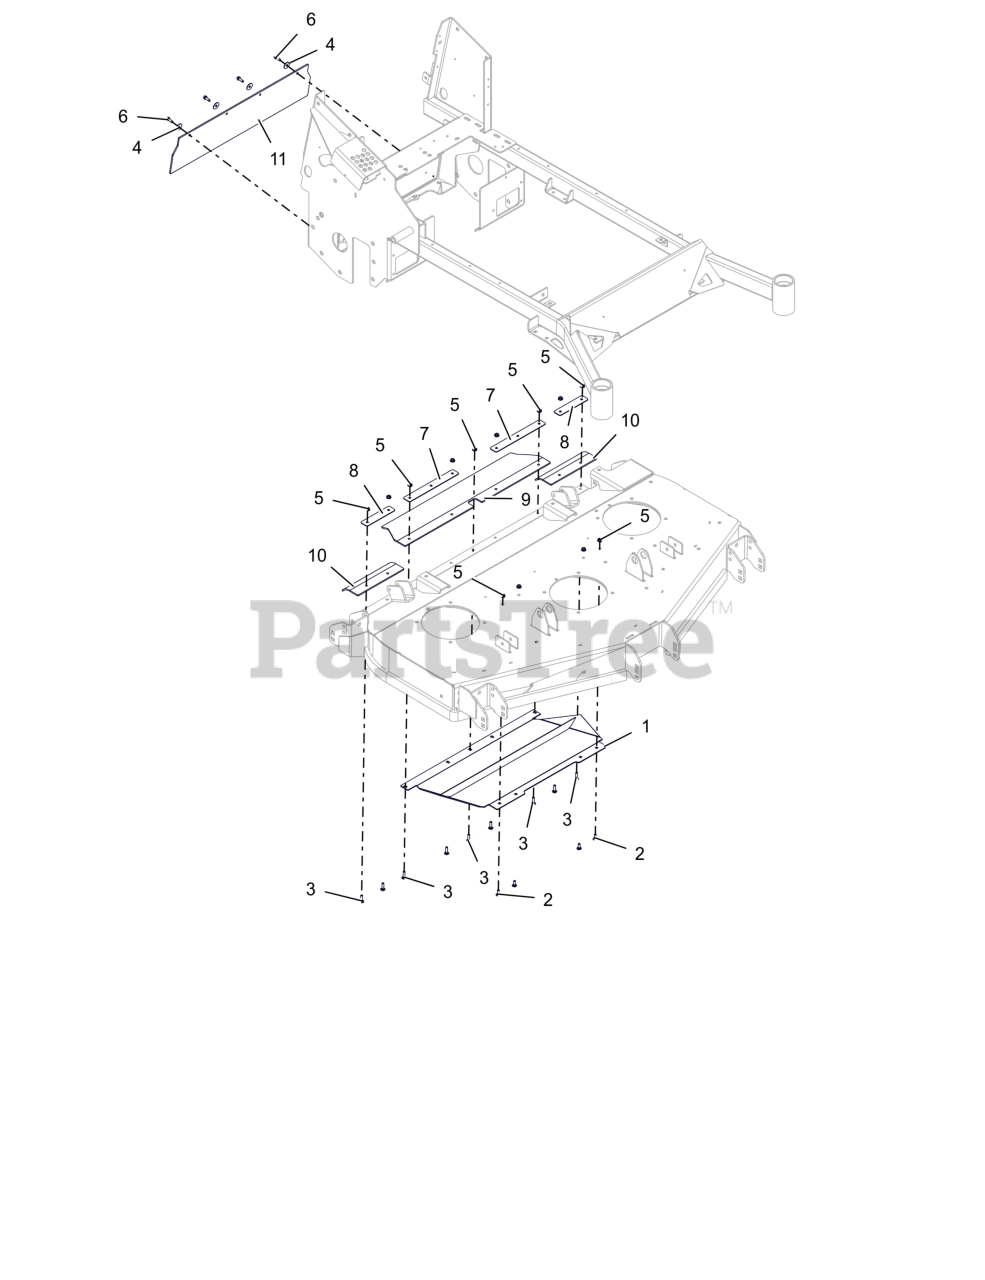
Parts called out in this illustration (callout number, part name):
1	WLDMT- 52" DEFLECTOR BAFFLE
2	BLT, RHSN .25-20X.750 G5 ZCC
3	BLT, RHSN .25-20X1.00 G5 ZCC
4	WSHR,FLT .281X1.000X.063 ZCC
5	NUT-LK-CTR-FLG .25-20 ZC120
6	SCR,TAP .25-20X.75 HWH TR ZCC
7	PLATE, CHUTE MTG (BLACK)
8	PLATE- 52" TIRE CHUTE MTG
9	CHUTE- REAR DISCHARGE 6.5 IN
10	FLAP- REAR DISCHARGE 52" TIRE
11	CHUTE, REAR DISCHARGE
